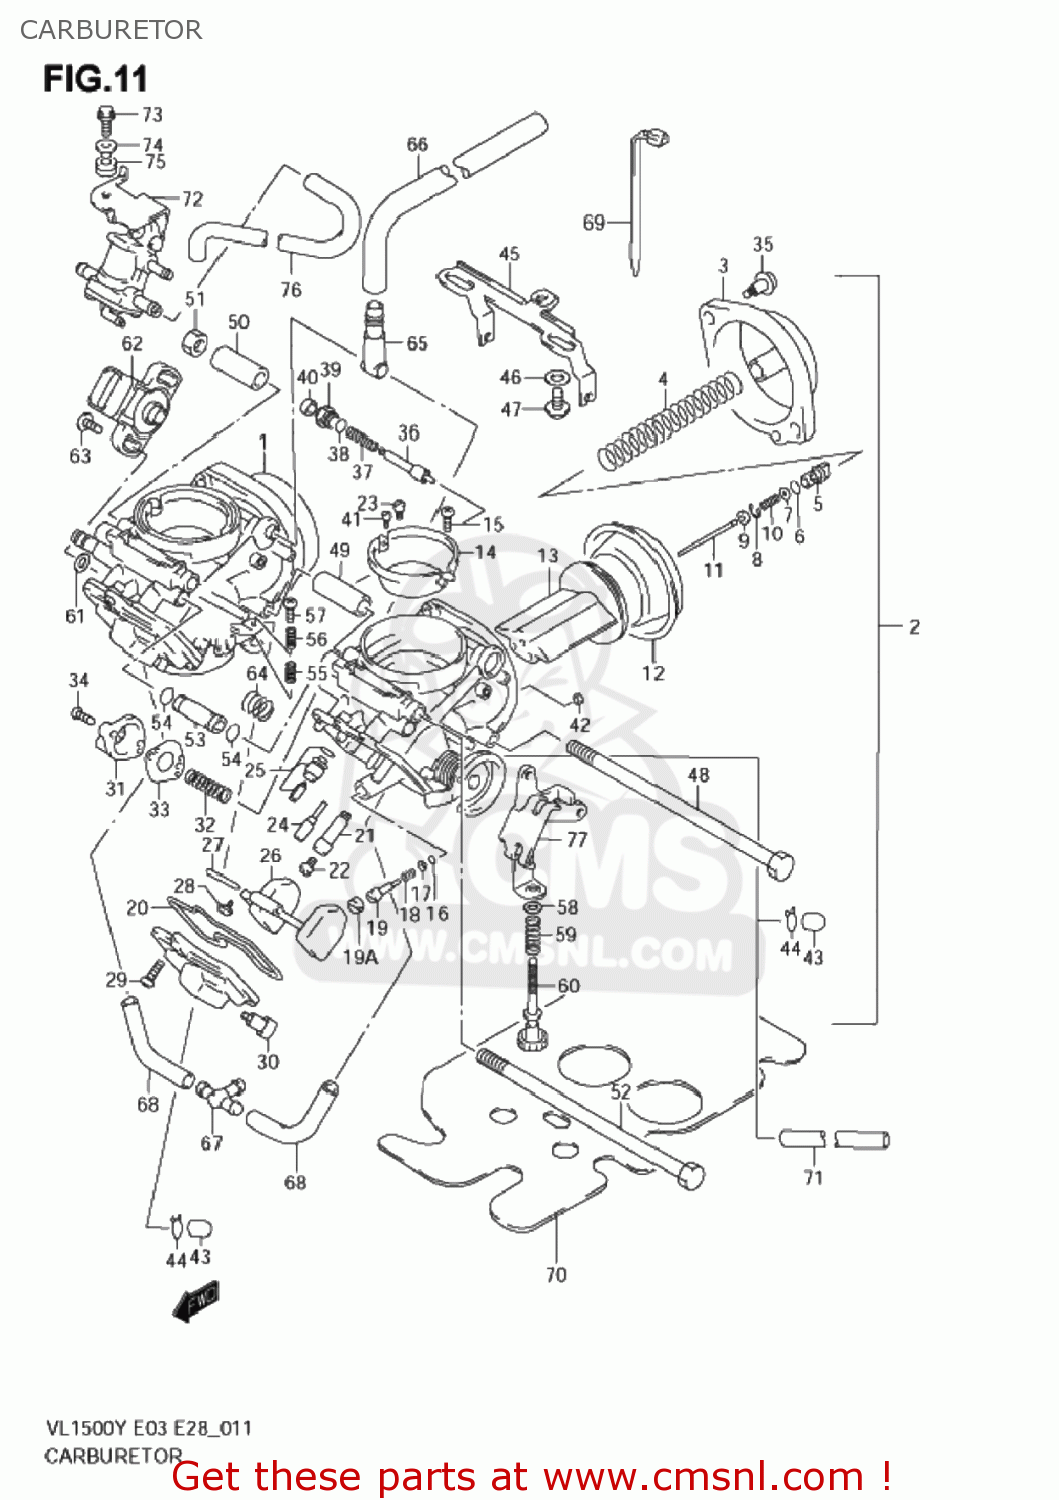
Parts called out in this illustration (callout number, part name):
1	CARBURETOR ASSY,R
2	CARBURETOR ASSY,L
3	COVER ASSY,DIAPHRAGM
4	SPRING
5	HOLDER
6	O RING(D:1.9,ID:4.8)
7	WASHER
8	E RING,MULTIPLE JET NOZZLE
9	RING
10	SPRING
11	NEEDLE,JET(5D95-56-1)
12	DIAPHRAGM
13	VALVE,PISTON
14	FUNNEL
15	SCREW
16	O RING,PILOT AIR SCREW
17	WASHER
18	SPRING,THROTTLE SCREW
19	ADJUSTER
19A	PLUG
20	O RING
21	HOLDER,JET
22	JET,MAIN(110)
23	JET,MAIN(55)
24	JET,PILOT(32.5)
25	VALVE ASSY,NEEDLE(NI)
26	FLOAT ASSY
27	PIN,FLOAT
28	SCREW
29	SCREW
30	SCREW,DRAIN
31	COVER ASSY
32	SPRING
33	DIAPHRAGM ASSY
34	SCREW
35	SCREW
36	PLUNGER
37	SPRING
38	O RING
39	GUIDE SCREW,PLUNGER
40	CAP,STARTER VALVE
41	JET,PILOT AIR(1.9)
42	O RING
43	CAP
44	CLIP
45	LEVER
46	PACKING
47	SCREW
48	BOLT
49	PIPE
50	PIPE
51	NUT
52	BOLT
53	PIPE
54	O RING
55	SPRING,THROTTLE SCREW
56	SPRING
57	SCREW
58	WASHER
59	SPRING
60	SCREW,ADJUST
61	GASKET,THRO VALVE INSPECTION (NAS)
62	SENSOR ASSY,THROTTLE
63	SCREW,SENSOR
64	SPRING
65	HOSE
66	HOSE
67	NIPPLE
68	HOSE(3.5X7.5X600)
69	CLAMP(L:125)
70	SHEET HEAT SHIELD
71	HOSE
72	VALVE,AIR VENT
73	BOLT
74	WASHER
75	CUSHION
76	HOSE(9X14X600)
77	BRACKET
78	BRACKET
